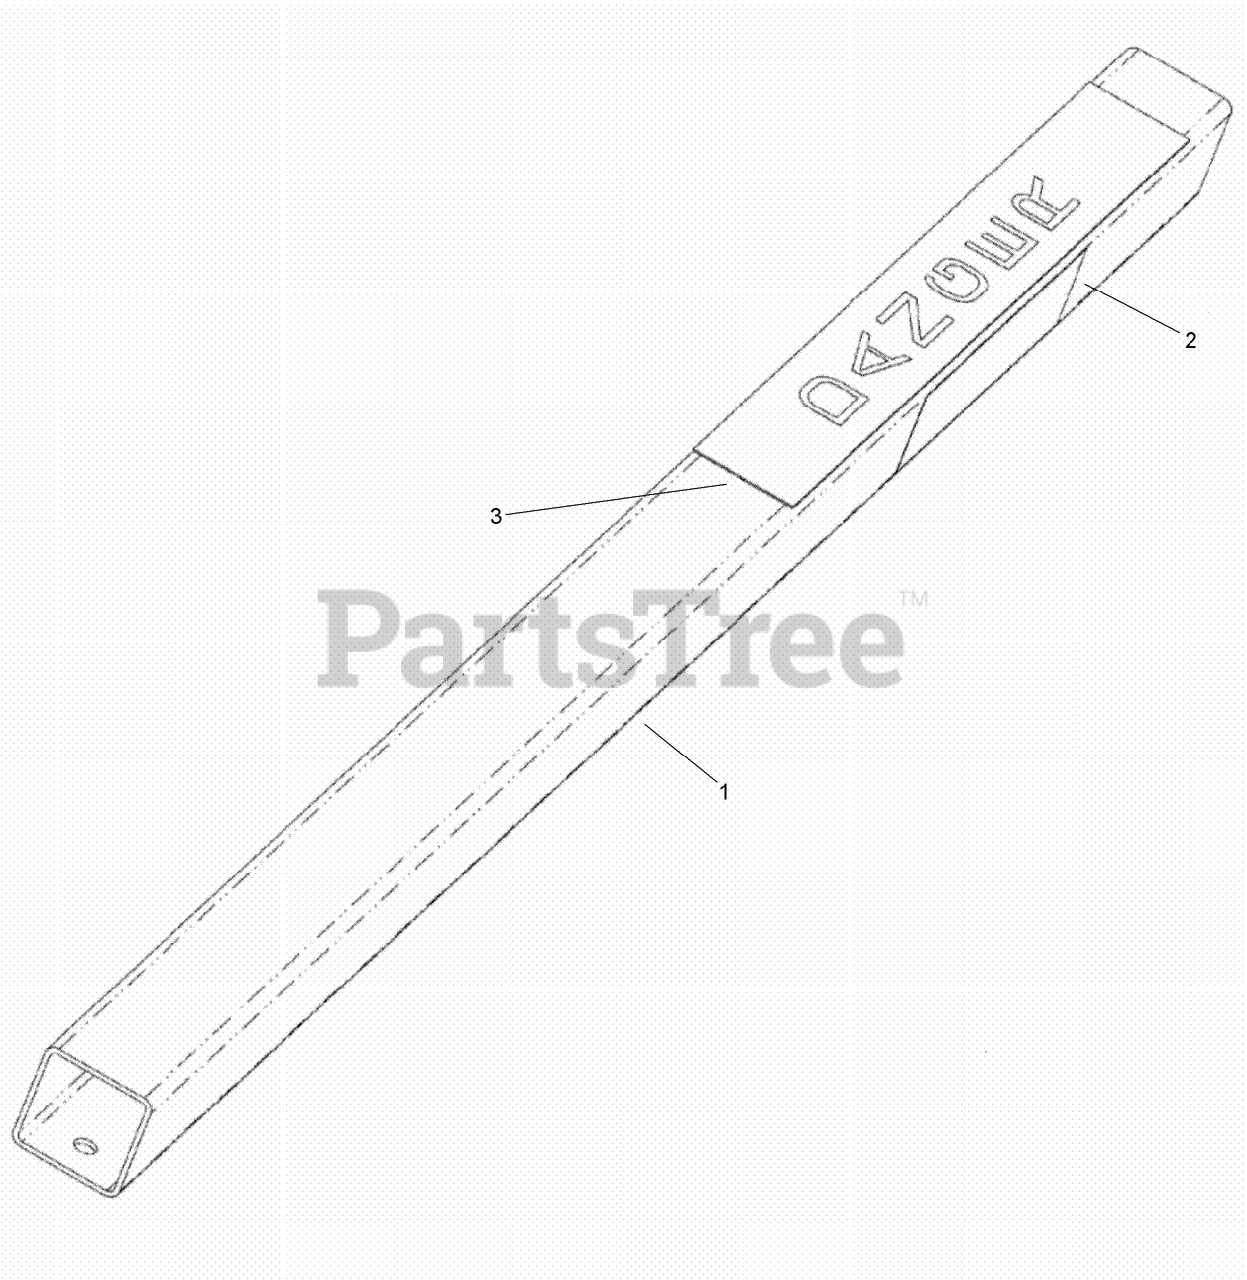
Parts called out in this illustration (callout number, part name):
1	TUBE-Restraint Bar
2	DECAL-Danger, Entanglement Hazard
3	DECAL-Danger
